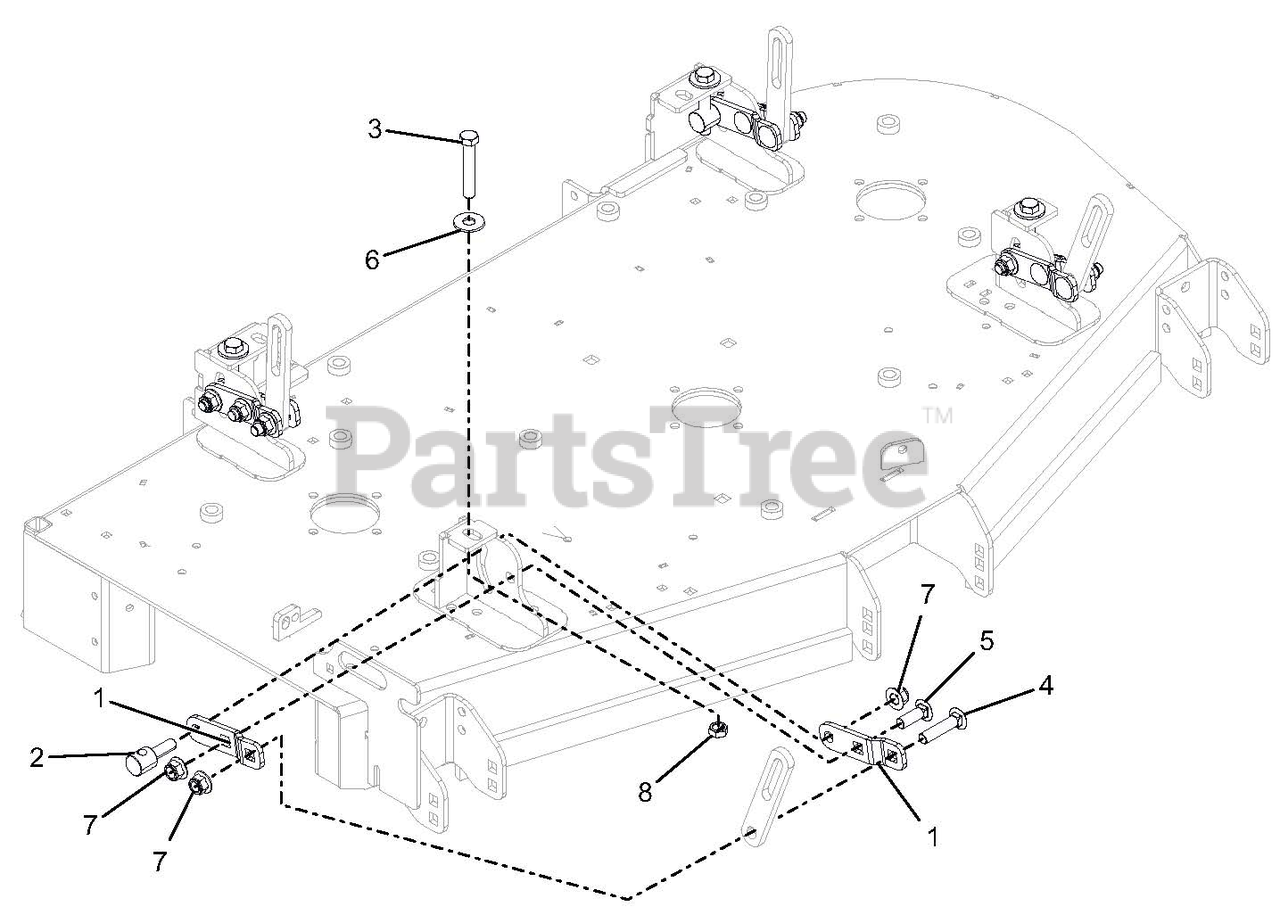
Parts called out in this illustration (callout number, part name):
1	DECK LEVELING BRACKET - BLACK
2	TRUNNION, .50-13
3	BLT,HEX .50-13X3.00 GR5 FTH YZ
4	BLT-RDHDSQNK .50-13X2.25 G5YZ
5	@BLT-RDHDSQNK .50-13X1.50 G5YZ
6	@WSHR-FL-STL.563X1.38X.109YWZC
7	@NUT-LK-NYL-FLG .50-13 YWZC
8	NUT-JAM .50-13 YWZC
